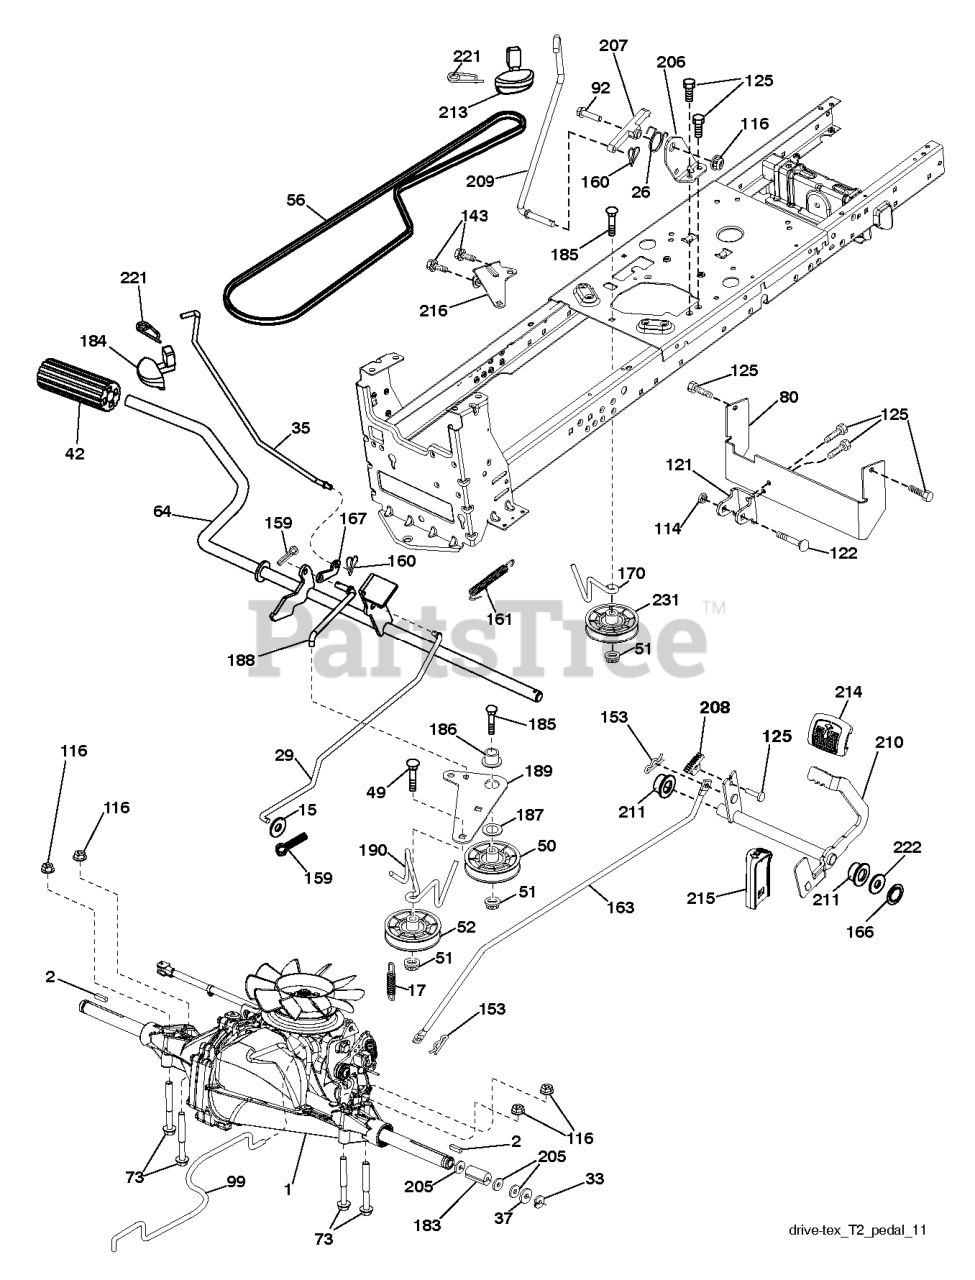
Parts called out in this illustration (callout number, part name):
2	SQUARE KEY
15	WASHER
17	SPRING.BRAKE.K46.GREEN
26	SPRING.RETURN.CRUISE
29	ROD.BRAKE.T2.TEX
35	ROD.BRAKE.PARKING.GT.H
42	PEDAL COVER T
50	IDLER.FLAT.910.OFFSET
51	NUT LOCK FLG 3/8-16 UNC
52	IDLER.V-GROOVE.910.OFFSET
56	V-BELT.MOWER.92.40.42/K46
64	SHAFT.ASM.PEDAL.BRK.CNTR
73	BOLT HEX 5/16-18 GR 5
80	STRAP TORQUE
92	BOLT
99	ROD.SPRING.BYPASS.K46.LT.Z
114	NUT.71038.31-18.HEX.NYLOCK
116	NUT LOCK HEX FLANGE 5/16-18
121	BRACKET STRAP TORQUE
122	BOLT.5/16-18X2.5
125	SCREW
143	Screw 5/16-18 x 1/2 Hex, Self Tapping 5/16-18 x 1/2
153	RETAINER M
159	COTTER PIN
160	RETAINER CLIP
161	SPRING, RETURN LT
163	ROD.CONTROL.PEDAL.K46
166	NUT.PUSH.625
167	LATCH.BRAKE.SPRING
170	KEEPER.CENTER SPAN.1.688
183	SPACER AXLE
184	HANDLE.PARKG.BRK.HUSQ X667
186	SPACER.RETAINER
187	WASHER 12/32X2X10GA
188	RP.LINK.CLUTCH.GROUND.DRIVE
189	BELLCRANK.GROUND.DRIVE.TEX.
190	KEEPER.BELLCRANK.DRIVE
206	BRKT.MOUNT.LATCH.CRUIS
207	LATCH.CONTROL.CRUISE
208	GEAR.SECTOR.CONTROL.CR
209	ROD.CONTROL.CRUISE.GT.
210	ROCKER.ASM.PEDAL.CONTR
211	BEARING.NYLON
213	KNOB.CONTROL.CRUSIE.HU
214	PEDAL.FORWARD.PAD.TEX
215	PEDAL.REVERSE.TEX.GT.4
216	BRACKET.PULLEY.IDLER.W/TEX
221	RETAINER.SPRING.CLIP.H
222	WASHER 21/32 X 1-1/4 X 10 GA.
225	KEEPER.BELT.TRANSAXLE.K46
226	BRACKET.MOUNT.TORQUE.K46.TLT
230	WASHER.HARDENED
231	IDLER.V-GROOVE.1.688.OFFSET
